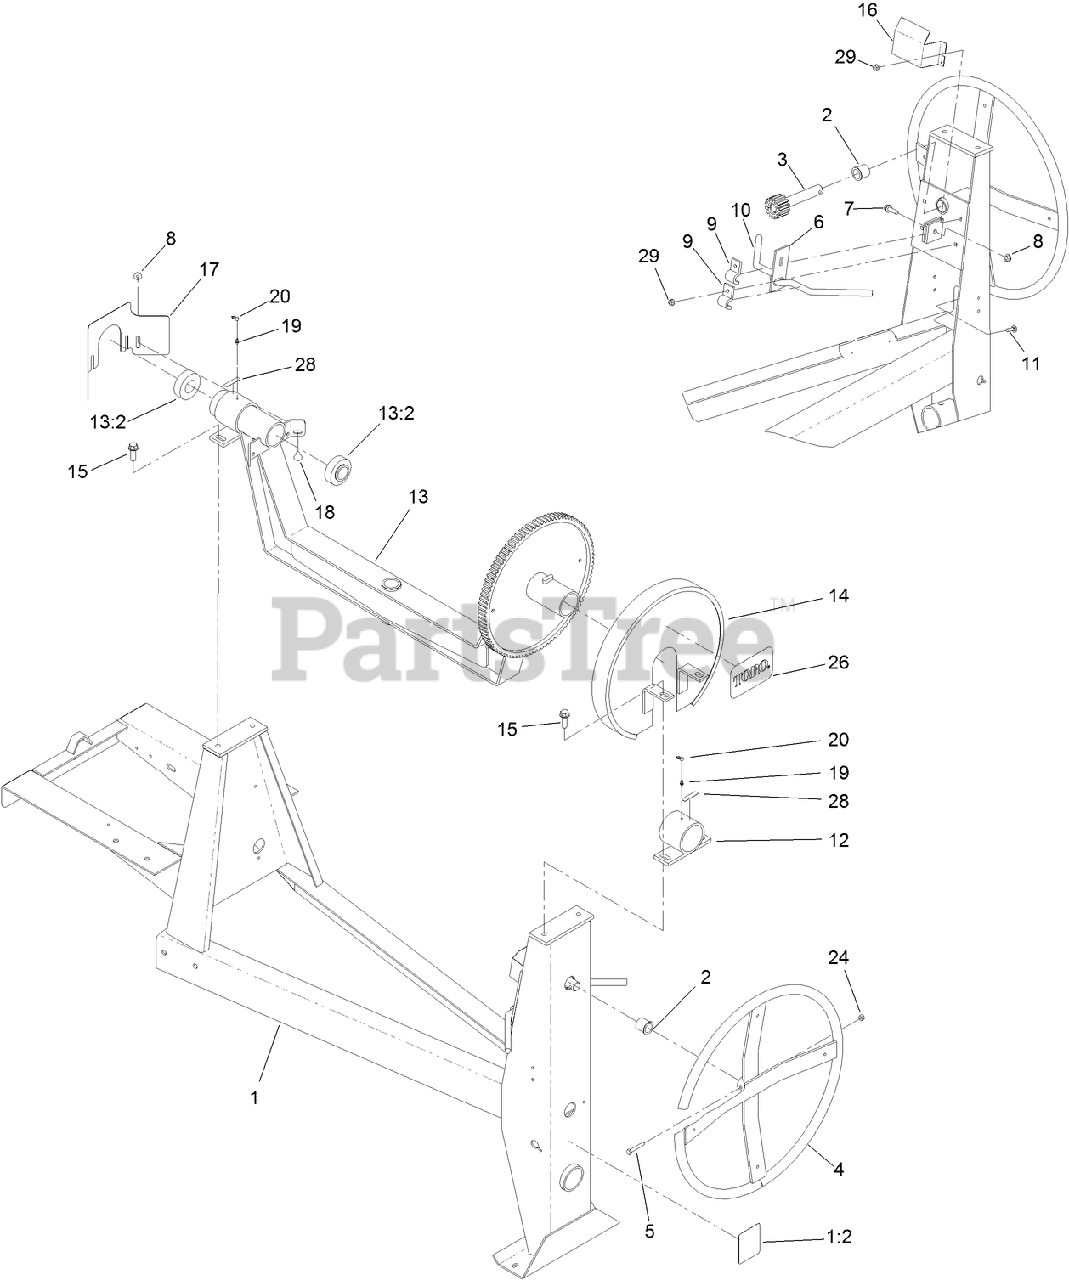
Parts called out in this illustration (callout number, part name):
1	FRAME ASM
1:2	DECAL-SAFETY CHAIN, TOWING
2	BUSHING-NYLON
3	SHAFT-TILT
4	HANDWHEEL
5	SCREW-HH
6	DOG-BRAKE
7	SCREW-HHF
8	NUT-HF, NI
9	BRACKET-HANDLE
10	HANDLE-BRAKE
11	BOLT-CARR
12	TRUNNION
13	YOKE ASM
13:2	BEARING
14	GUARD-BRAKE, UPPER
15	SCREW-HWH
16	GUARD-BRAKE, LOWER
17	GUARD-PINION
18	SCREW-CARR
19	FITTING-GREASE
20	CAP-PLUG
24	NUT-LOCK, NI
26	DECAL
28	DECAL-GREASE
29	NUT-HF, NI
